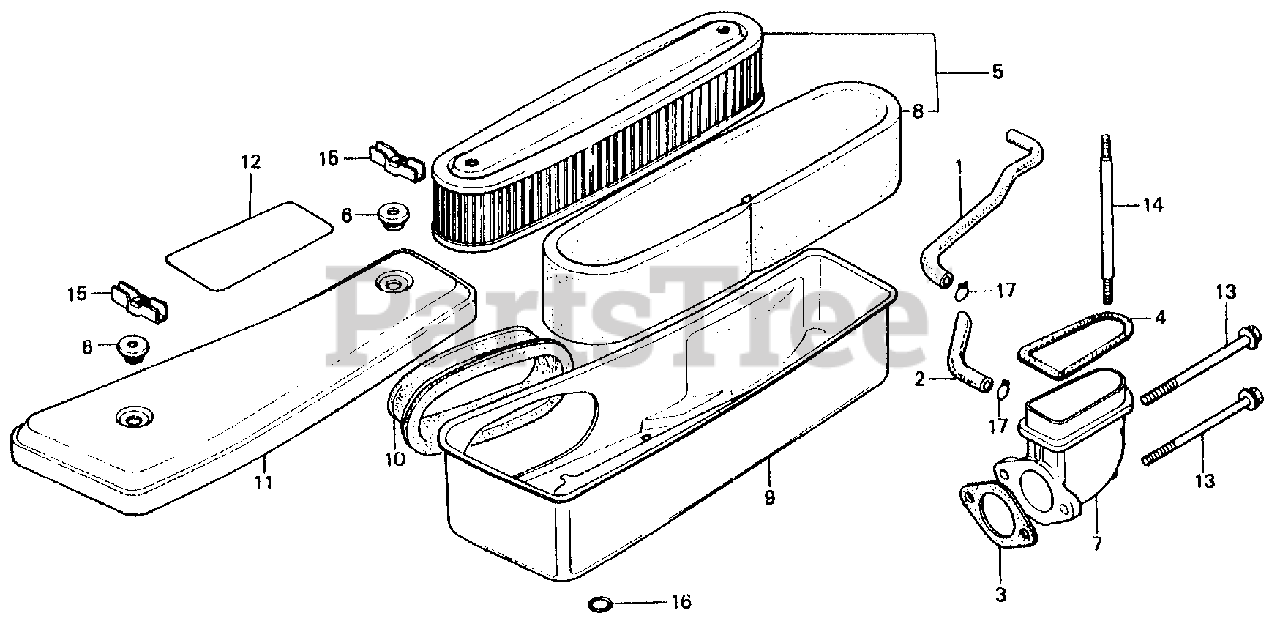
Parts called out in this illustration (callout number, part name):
2	TUBE, BREATHER
3	GASKET, AIR CLEANER
4	GASKET, AIR CLEANER ELBOW
5	ELEMENT, CLEANER
6	GROMMET, AIR CLEANER
7	ELBOW, AIR CLEANER
8	FILTER (OUTER)
9	HOUSING, AIR CLEANER *NH105* (MAT BLACK)
10	INLET, AIR
11	COVER, AIR CLEANER *NH105* (MAT BLACK)
12	MARK, AIR CLEANER CAUTION
13	BOLT, FLANGE (6X93)
14	BOLT, STUD (6X121)
15	WINGNUT, AIR CLEANER COVER
16	O-RING (5.1X2.2) (NOT AVAILABLE)
17	CLIP, TUBE (B12.5)
